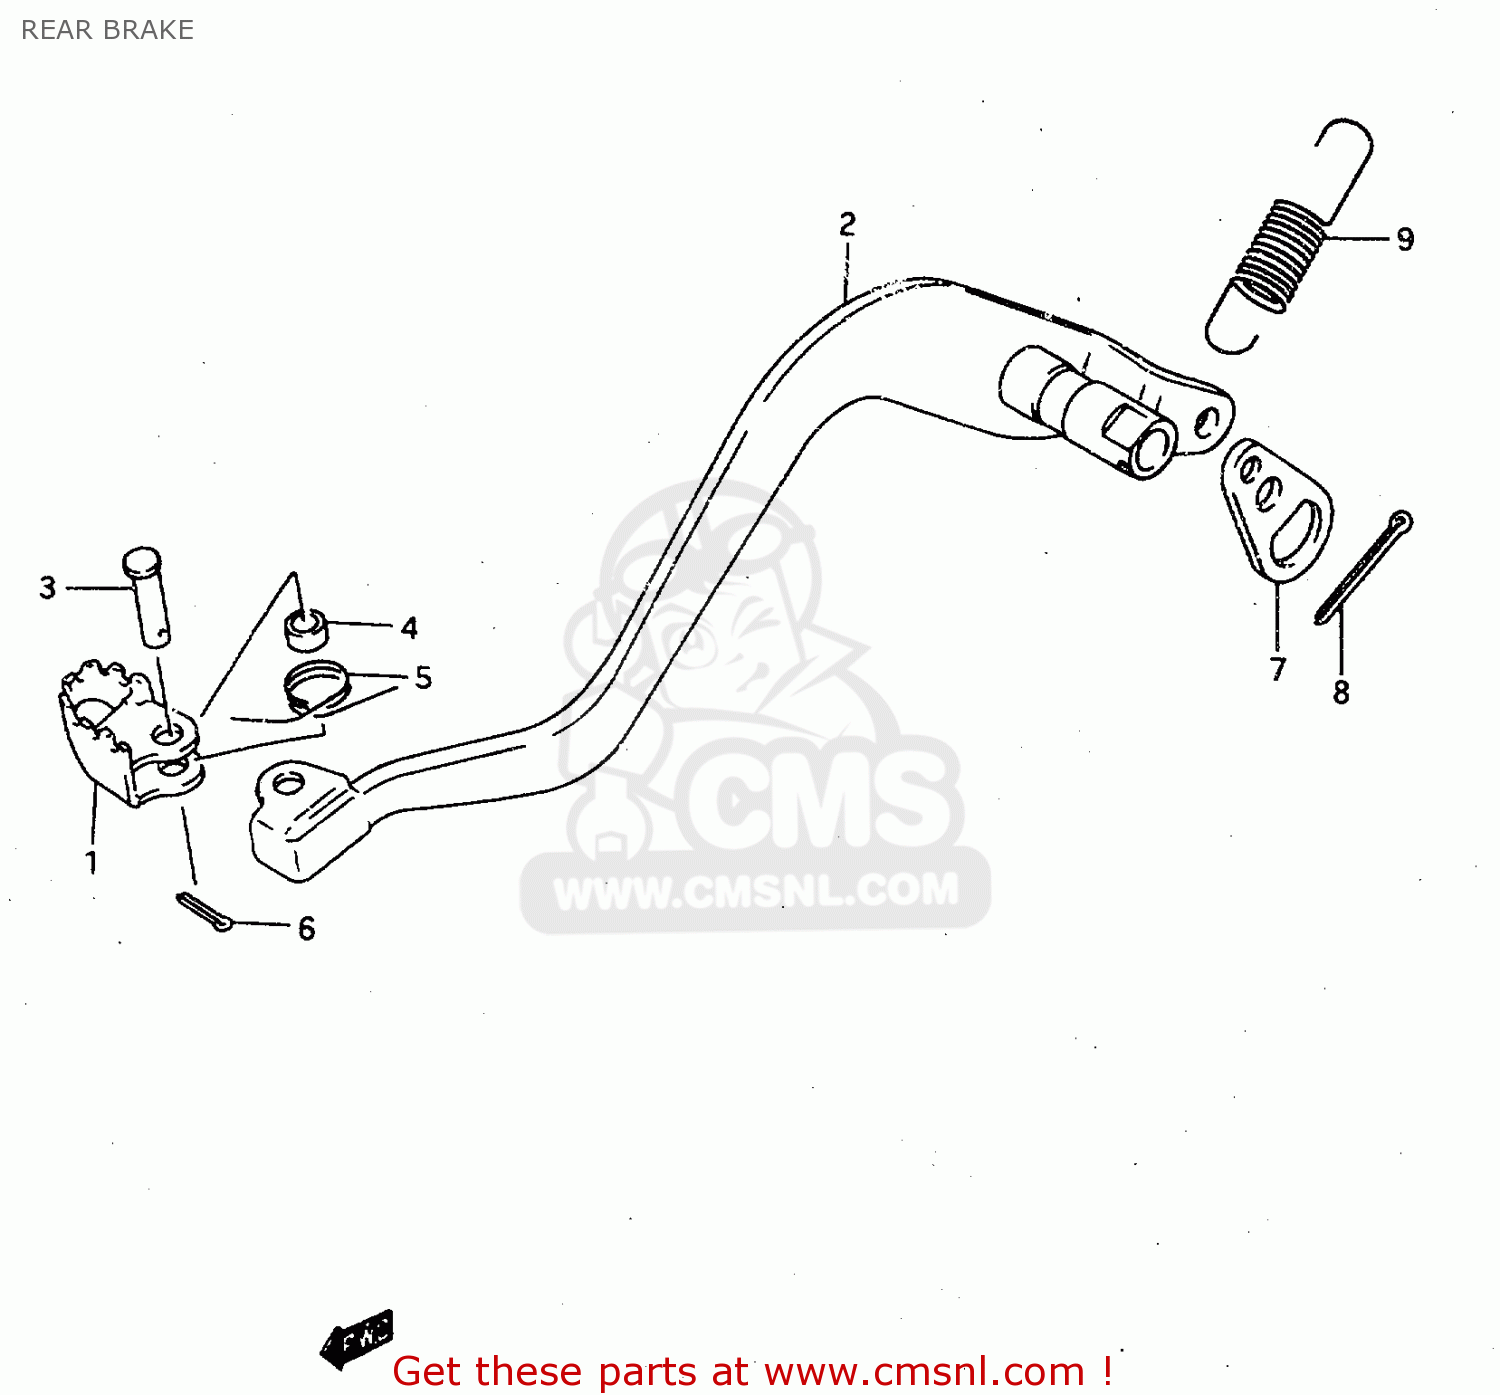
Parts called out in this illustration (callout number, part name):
1	PEDAL,BRAKE
2	ARM, BRAKE PEDAL
3	PIN
4	SPACER(9.2X9X6.5)
5	SPRING
6	PIN
7	PLATE, BRAKE PEDAL
8	COTTER PIN
9	SPRING
